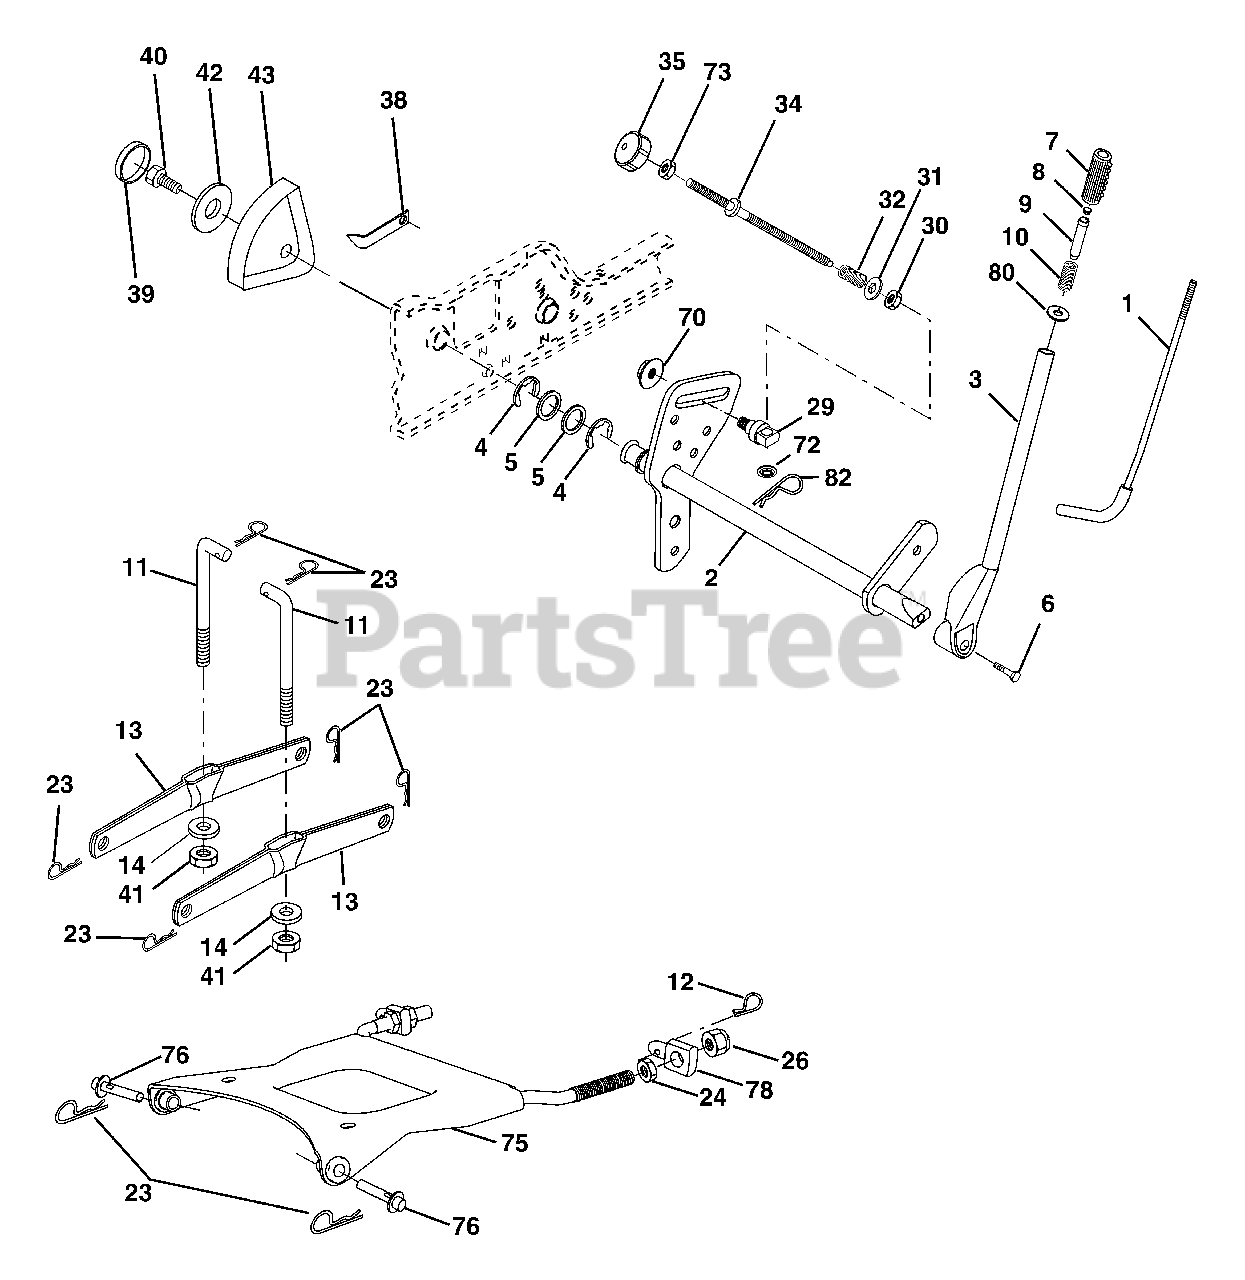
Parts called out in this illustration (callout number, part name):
1	Rod Asm., Lever
2	Shaft Asm., Lift Vgt
3	Lever Asm., Lift Rh
4	E-Ring Truarc #5133-87
5	Washer 29/32 x 1-1/4 x 16 Ga.
6	Bolt, Fin Hex 3/8-16 x 1-1/2
7	Grip, Handle
8	Button, Plunger
9	Plunger, Lever Lift
10	Spring 2-1/8"
11	Link Lift
12	Retainer, Spring
13	Arm Assembly Suspension Mower
23	Retainer, Spring
24	Nut, Jam Hex 1/2-13 Unc
26	Nut, Lock W/Wsh 1/2-13 Unc
29	Trunnion Infin Height
30	Nut, Special
31	Washer 13/32 x 5/8 x 16 Ga.
32	Spring, Compression Inf Hgt
34	Rod, Adj Lift
35	Knob, Inf 3/8-16 Unc
38	Pointer Height Indicator
39	Plug, Hole Blk. 1.485/1.515 Dia.
40	Screw 5/16-18 x 1
41	Nut Crownlock 3/8-24
42	Washer 11/32 x 1-1/2 x 10 Ga.
43	Scale, Indicator Height
70	Nut Hex Flange Lock
72	Nut Push Phos & Oil
73	Nut, Hex Jam 3/8-16 Unc
75	Plate, Asm, Susp, Front
76	Pin Flange
78	Trunnion, Front, Susp
80	Washer 1/4 x 5/8 x .062\
82	Retainer Clip
